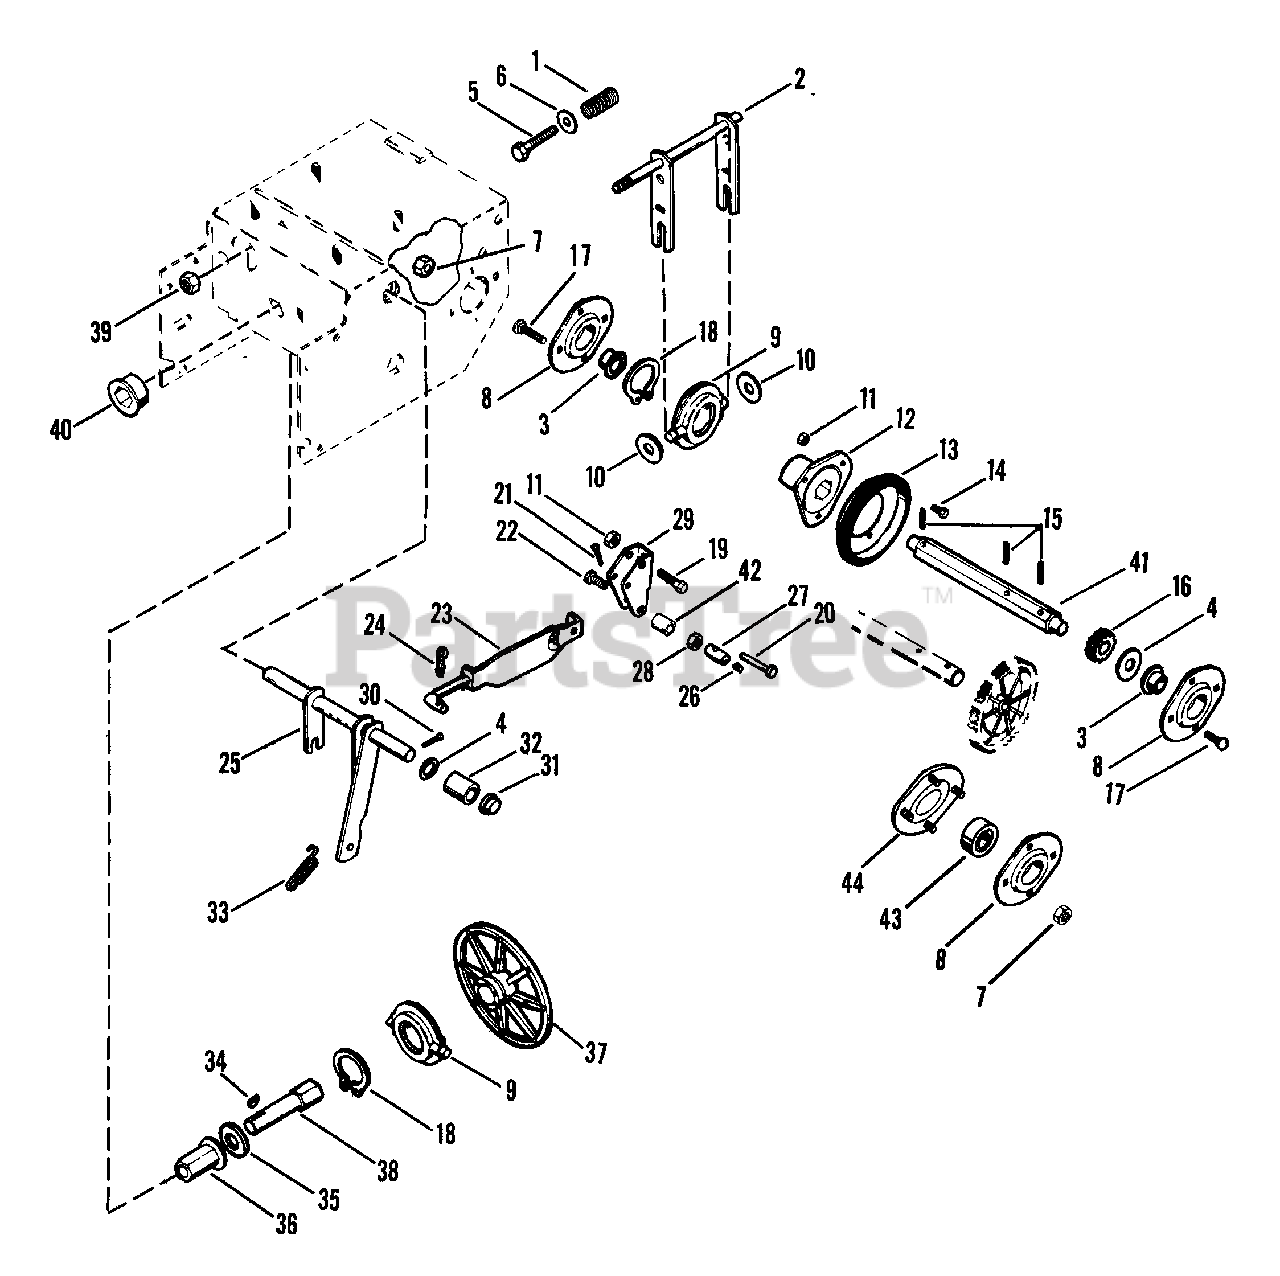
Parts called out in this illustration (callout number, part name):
1	SG-COMP .105X.585X.75
2	SHIFTING FORK
2	SHIFT FORK
3	BSHG-FLG .500X.750X.625X.937
4	WSHR-FL-STL .531X1.062X.095 PL
5	BLT-HEX .31-18X1.50 PL GR2
6	WSHR-FL-STL.344X.688X.065PL
7	NUT-LK DUAL FACE 10-24 PL
8	BUSHING FLANGE
8	BEARING FLANGE
9	BEARING ASSEMBLY
10	WSHR-FL-STL .505X1.000X.062
11	NUT-LK-CTR .250-20 PL
12	FRICTION WHEEL HUB
13	FRICTION DISC
14	BLT-HEX .25-20X.50 PL GR2
15	PIN-ROLL .125X.88
17	BLT-RDHDSQNK 10-24X.38 PL
18	RG-RTNG-EXT 1.250X.050
19	BLT-HEX .25-20X1.75 PL GR2
20	CLEVIS PIN
21	PIN COTR .09X.50 PL
22	BLT-HEX .31-18X1.50 PL GR2
23	TRACTION CLUTCH ASSEMBLY
24	PIN-HAIR INT .08X.18X1.18
25	CLUTCH FORK
26	SCR-SET .32-18X.38 SKHCUPNL OH
27	ROD ADAPTER
28	NUT-LK .312-18 GR A PL
29	BRACKET
30	PIN-COTR .12X1.0 PL
31	CAP, .50 ROD YWZC
32	BSHG, SPCR.500X.750X.321 PM
33	SG-TENS .063X.44X1.56
34	KEY-WDRF .188X.75X.313 SAE 9
35	WSHR, THRUST .625X1.125X.063
36	BSHG-FLG .625X.875X1.750X1.188
37	FRICTION PLATE
38	HEX SHAFT
39	NUT-LK-CTR .375-16 GR A PL
40	BSHG-FLG .875X1.25X.75X1.50HX
41	HEX SHAFT
42	SPACER -SPLIT .340X.490X1.02
43	BRG-BALL .500X1.38X.437
44	BEARING FLANGE
